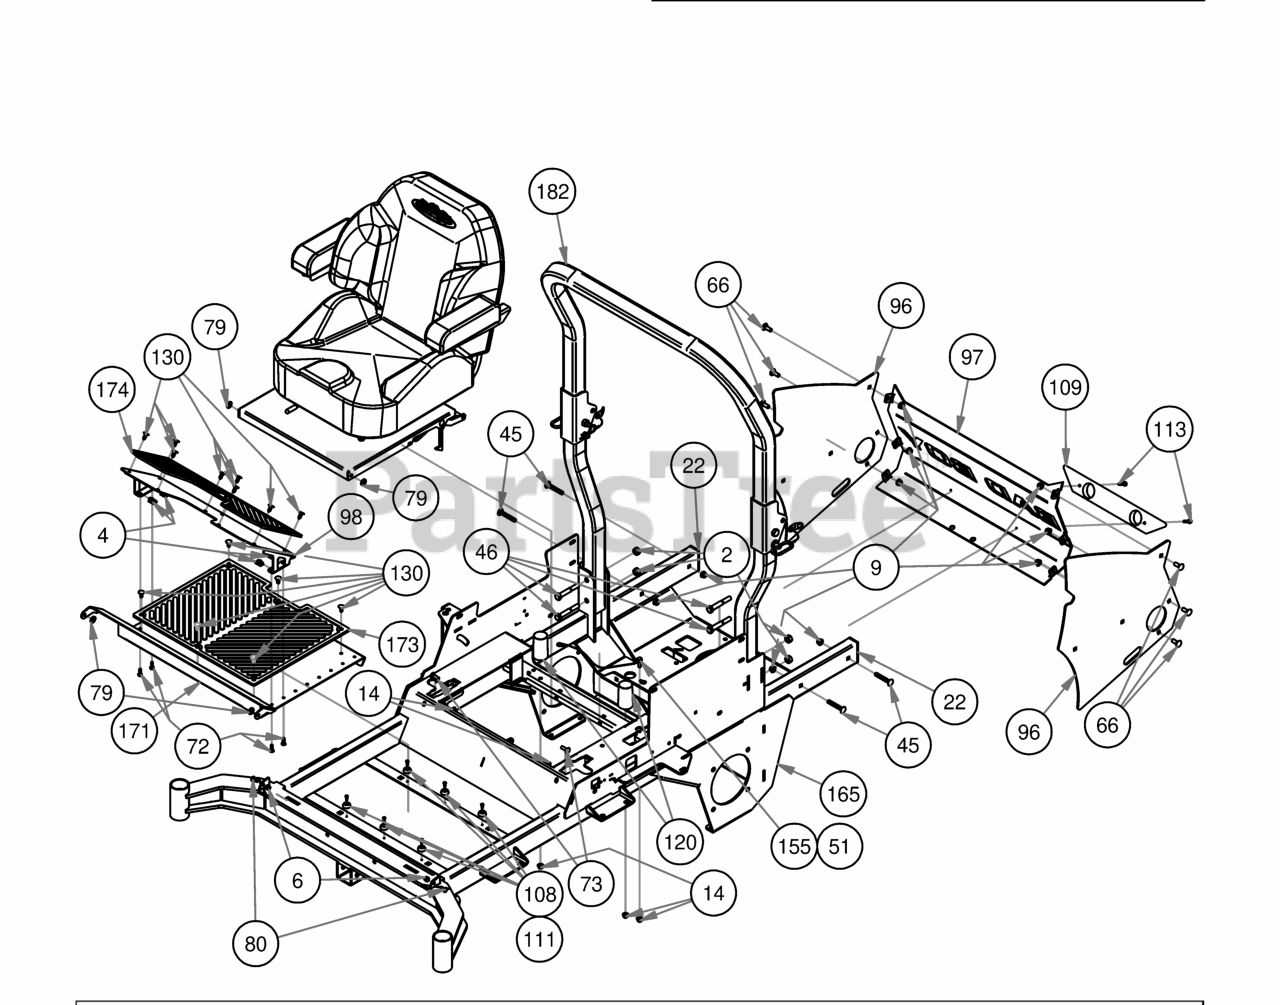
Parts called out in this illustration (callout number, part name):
2	1/2" Center Lock Nut
4	1/4-20 Cage Nut
6	1/4-20 Nylon Insert flange Nut
9	3/8" Nylock Flange Nut
14	5/16" Nylon Flange Nut
17	5/16" Flange Nut
19	5/16-18 Nylock Jam Nut 1/2 Nut
22	1 1/2 x 3 Frame Plug
42	M6-1.0 X 16MM Hex Bolt
45	3/8" x 2 1/2" Carriage Bolt
46	1/2-13 X 3.25 Hex Bolt - Grade 5
51	5/16" x 1" Bolt
62	5/16" x 1 1/4" Carriage Bolt
66	3/8" x 1" Carriage Bolt
72	1/4" x 3/4" Hex Bolt
73	5/16" x 1" Carriage Bolt
79	.360 ID Plastic Washer
80	1/4" x 3/4" Carriage Bolt
95	2019 Outlaw Seat Plate
96	2019 Rebel Rear Cover Side Plate
97	2019 Vertical Rear Cover Tailgate Plate
98	2019 Outlaw Adjustable Foot Plate
105	Seat Latch Rod Assembly
108	Button Bumper
109	2017 XP Bumper
111	#10 x 1/2" Self Tapping Screw
113	1/4 x 1 Hex Head Tek screw
120	2019 Bad Boy X Cylindrical Seat Mount
124	Brake Spring
130	Ratchet Fastener
155	Seat Cable
156	2019 Outlaw EPA Cannister Assembly
165	2019 Rigid Frame
166	2019 Rebel Seat
167	2019 Renegade Seat
171	2019 Outlaw Floorboard
173	OUTLAW2019_FLOORMAT
174	FLOORMAT_OUTLAW_2019
182	2019 2X2 Folding ROPS
